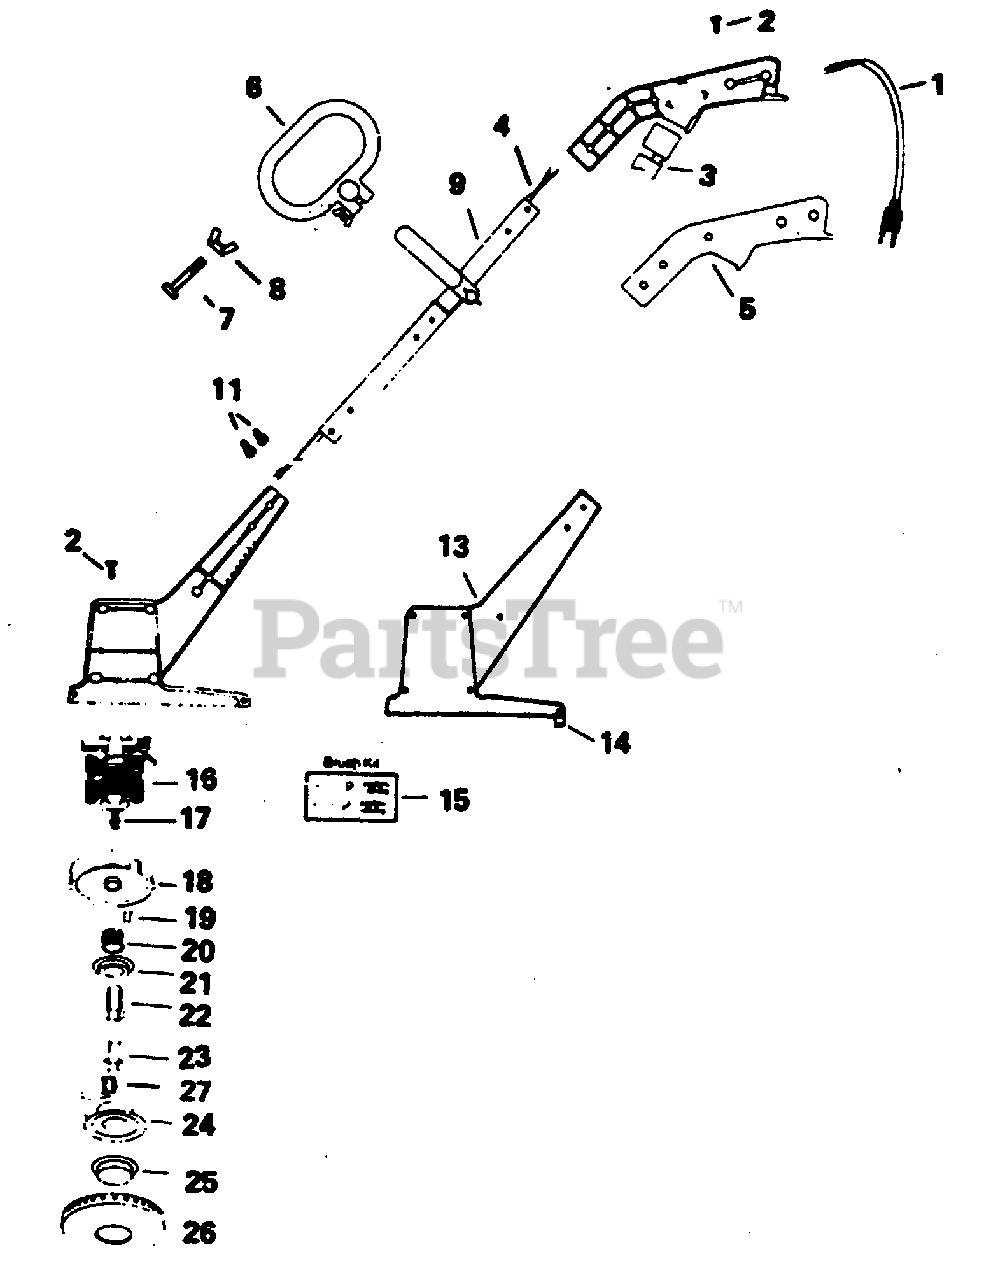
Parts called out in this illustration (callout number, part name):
1	POWER SUPPLY CORD
5	TRIGGER HANDLE SET
6	ASSIST HANDLE
7	BOLT (1-1/2")
8	WING NUT
11	CONNECTOR
13	MOTOR HOUSING SET
14	TAIL INTERFERENCE BLADE
15	BRUSH KIT
17	WASHER, THRUST
19	LINE SAVER
20	COIL SPRING
21	COIL SPRING ADAPTOR
22	DRIVE GEAR
23	DRIVE GEAR INSERT
24	SPOOL WOUND
25	RELEASE BUTTON
27	DRIVE ADAPTOR INSERT
